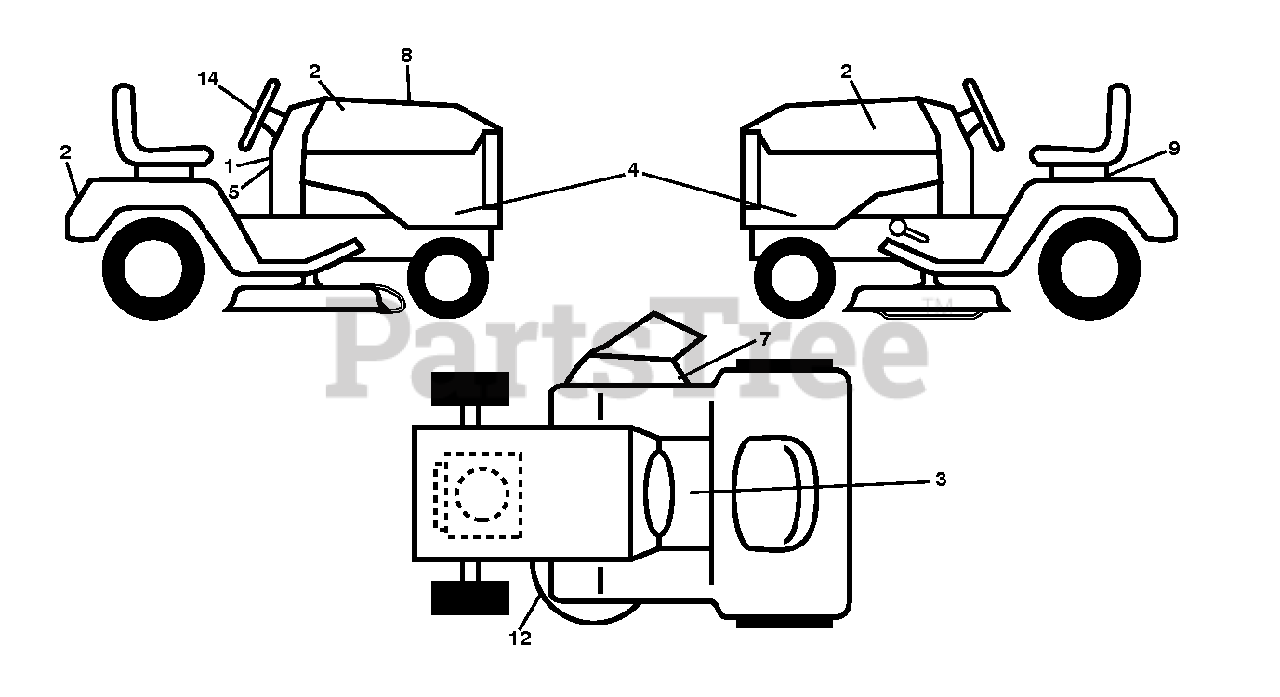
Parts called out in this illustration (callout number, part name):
5	DECAL, WARNING SPARK ARRESTOR
7	DECAL
9	DECAL BTRY SYMBOLS
12	DECAL V BELT SCHEMATIC
